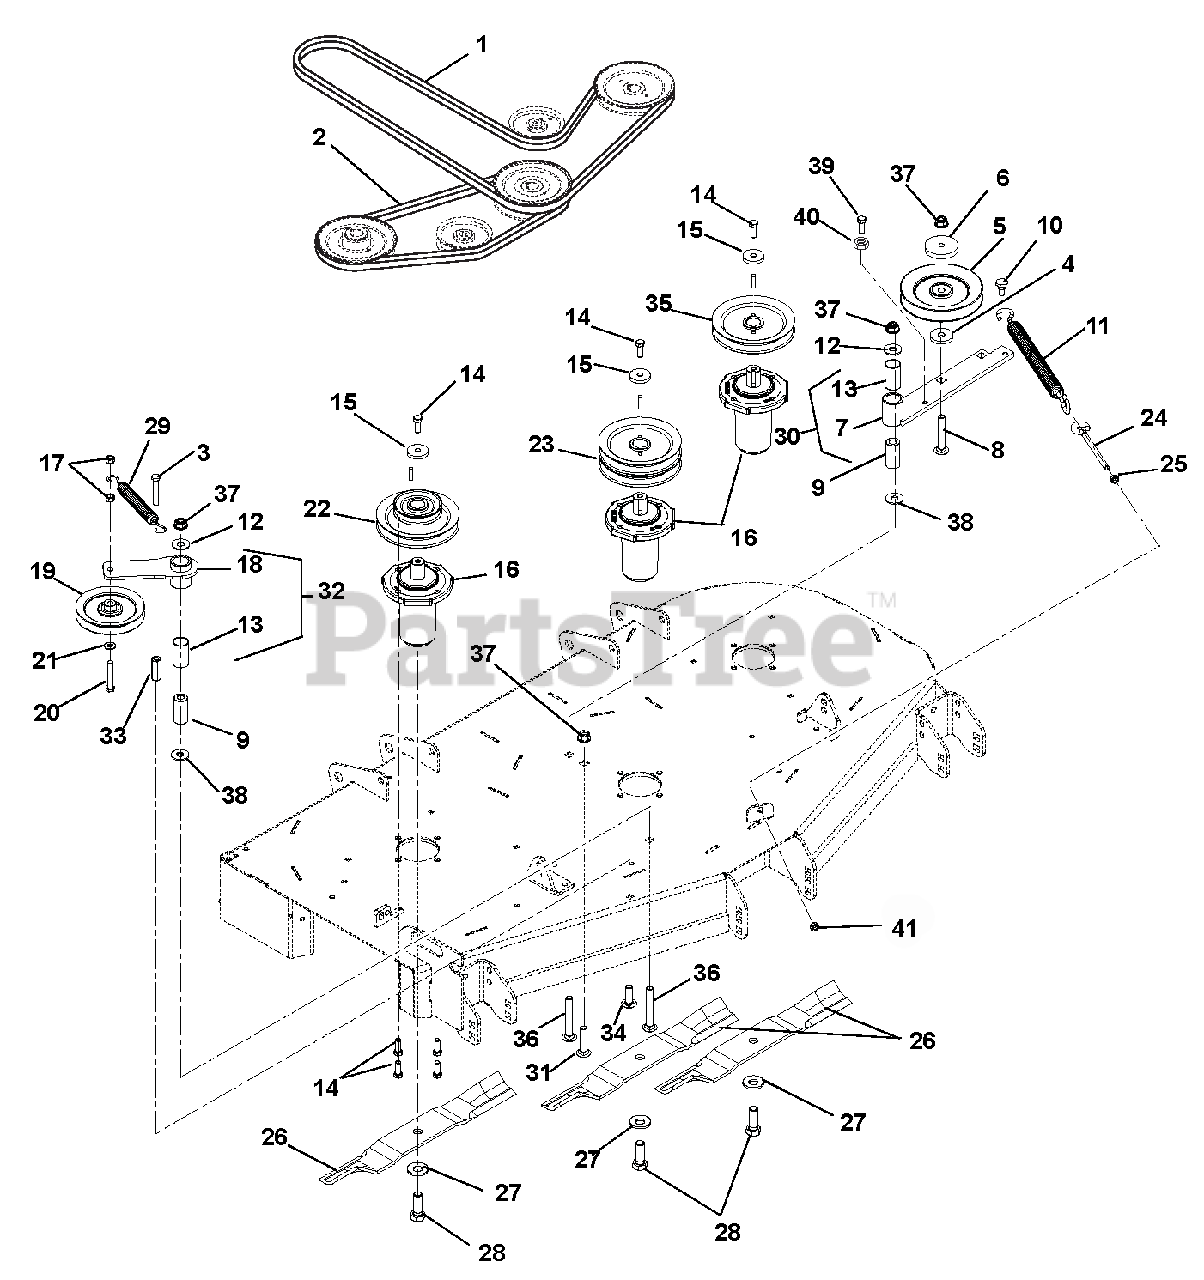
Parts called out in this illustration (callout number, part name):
1	HEX BELT, BB-WRAPPED
2	V-BELT, B-COGGED
3	@BLT-HEX .38-16X1.50 GR5 YWZC
4	BSHG, SPCR .502X.997X.50 PM
5	SHV, .50"ID X 6.00"OD V-IDLER
6	CAP, IDLER BEARING SEALING
7	WMT, IDLER ARM
8	@BLT-RDHDSQNK .50-13X3.00 G5YZ
9	BSHG, SPCR .502X.997X2.03 PM
10	BLT,SHLDR EP .38-16X.30 HEX YZ
11	SPRING, EXTENSION
12	@WSHR-FL-STL.563X1.38X.109YWZC
13	BSHG, 1.00 X 1.125 X 1.937
14	BLT-HEX .38-16X1.0 GR8 YZ EP30
15	WSHR,FLT STL.406X1.50X.245YWZC
16	ASM,MAINT FREE SPINDLE
17	@NUT-LK-CTR .38-16 YWZC
18	WMT, IDLER ARM
19	SHV, .38"ID X 5.00"OD V-IDLER
20	@BLT-HEX .38-16X2.25 GR5 YWZC
21	@WSHR-FL-STL.406X.812X.065 YWZ
22	PULLEY, DBL-1"IDX6.75"&4.25"OD
22	PULLEY, DOUBLE-1"IDX3.50"&6.0
23	PULLEY, DOUBLE-1"ID X 6.75"OD
23	PULLEY, DOUBLE
24	BOLT, .38-16X4.50 .62 DIA EYE
25	NUT-HEX-JAM .375-16 YWZC
26	BLADE, 20.5"
26	BLADE, 18"
27	WSHR-BLVL .669X1.535X.138
28	BLT-HEX .62-18X1.75 GR8 YWZC
29	SPRING, EXTENSION
30	ASM, IDLER PIVOT ARM (PTO)
31	BLT-RDHDSHSQNKFT.50-13X1.50 G5
32	ASM, IDLER ARM (DECK)
33	NUT COUPLING .375-16X1.75
34	@BLT-RDHDSHSQNK.38-16X1.0 G5YZ
35	PULLEY, V-1" ID X 6.75" OD
35	PULLEY, SINGLE-1"ID X 6" OD
36	@BLT-RDHDSQNK .50-13X3.50 G5YZ
37	@NUT-LK-NYL-FLG .50-13 YWZC
38	WSHR-FLT .640X1.75X.250
39	@BLT-HEX .38-16X2.75 GR5 YWZC
40	@NUT-HEX .38-16 YWZC
41	@NUT-LK-CTR-JAM .375-16 YWZC
